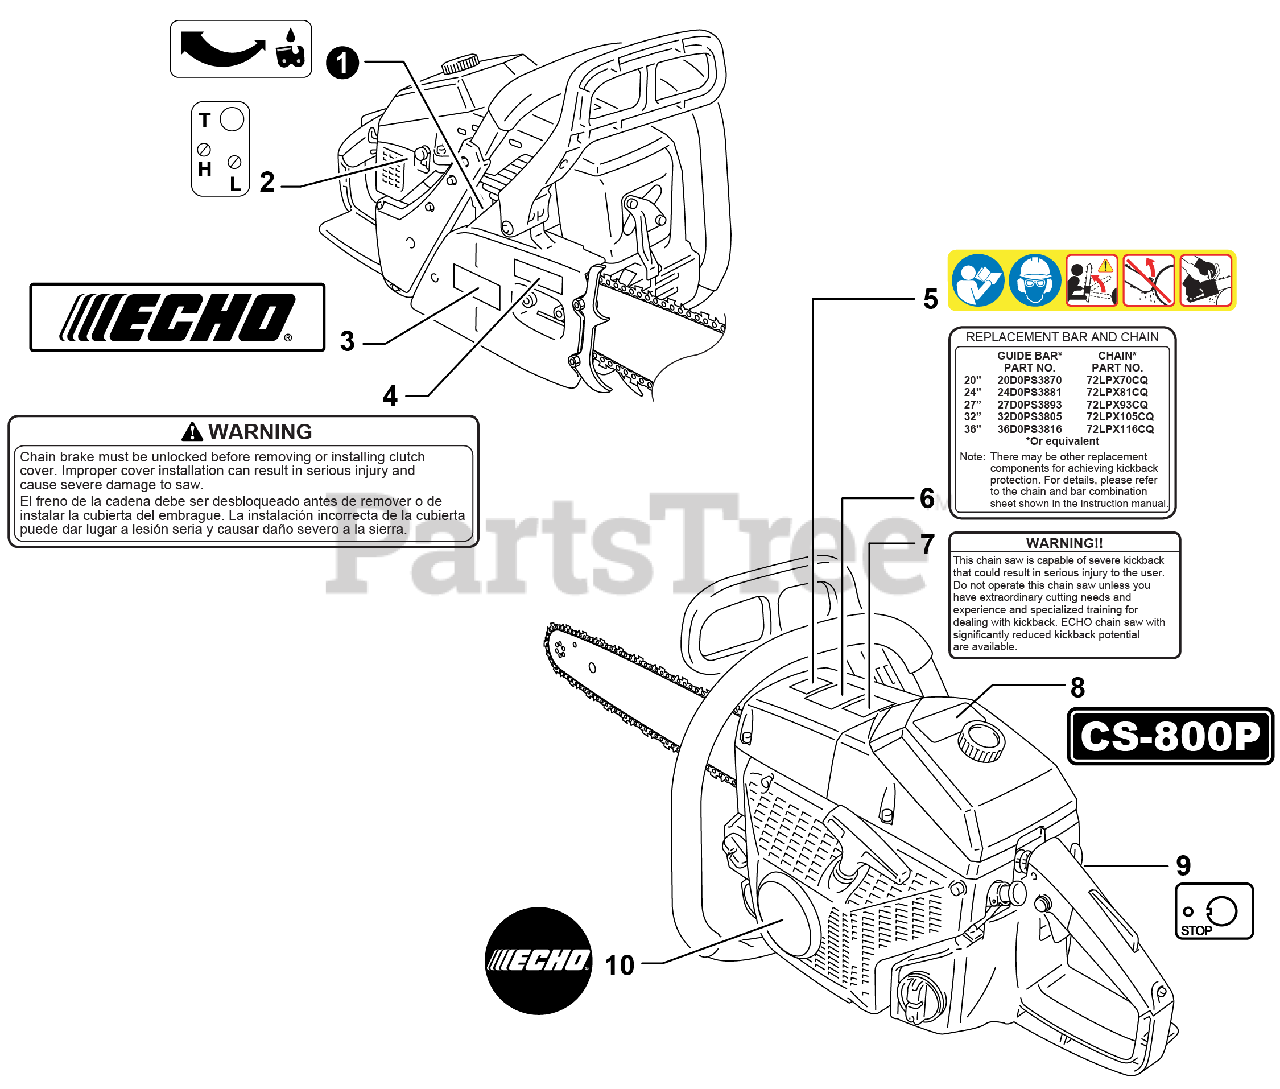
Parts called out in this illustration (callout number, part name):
1	LABEL, OILER
2	LABEL, CARBURETOR
3	LABEL, ECHO
4	LABEL, WARNING
5	LABEL, CAUTION
6	LABEL, BAR & CHAIN
7	LABEL, KICK BACK WARNING
8	LABEL, CS-800P
9	LABEL, STOP
10	LABEL, ECHO
